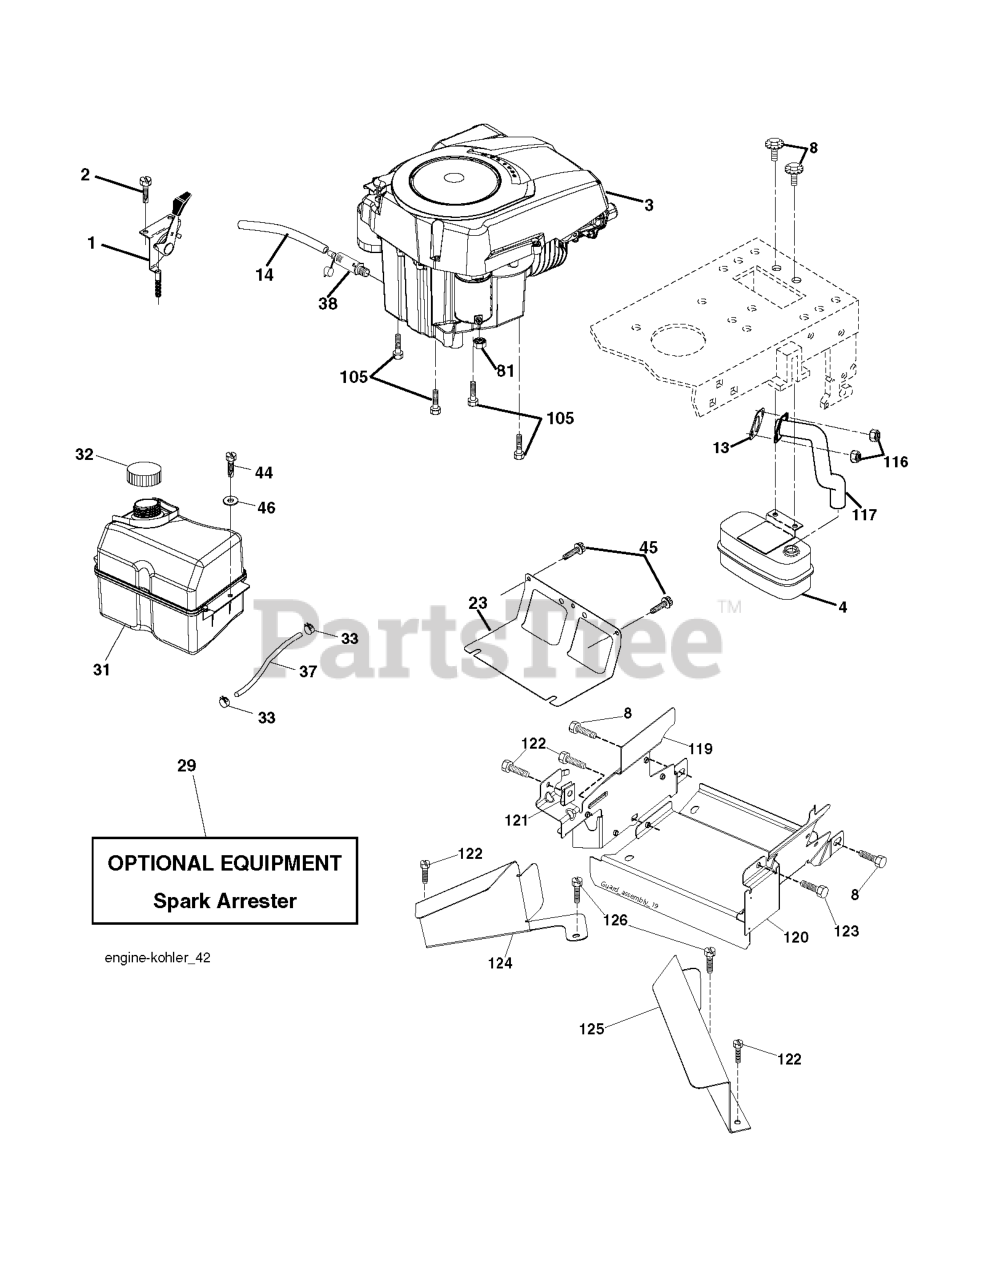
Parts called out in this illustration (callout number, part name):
1	CONTROL.TH/CK.C.
2	SCREW
4	MUFFLER.SINGLE.CYL.KOHL/B&S
8	BOLT.5/16-18UNCX3/4 W/SEMS.BLK
13	GASKET.EXHAUST.KOHLER
14	TUBE, DRAIN OIL ASM.
23	SHIELD.BROWNING.DBR.GUARD
29	KIT.SPARK ARRESTOR 794945 B&S
31	RP TANK FUEL FRT 1.5 GAL
32	FUEL CAP
33	HOSE CLAMP
37	LINE.FUEL.20
38	PLUG DRAIN OIL EASY
44	SCREW HEXWSHR 1/4-20X3/4
45	SCREW, 3/8-16X3/4
81	NUT
105	SCREW 3/8-16X1
116	NUT.HEX.FLANGE.TOPLOCK
117	RP.TUBE.EXHAUST.KOHL.COURAGE
119	LENKRAD
120	GUARD 532199767
122	SCREW.1/4-20X5/8
123	SCREW, 5/16-18 X 1/2
126	SCREW
